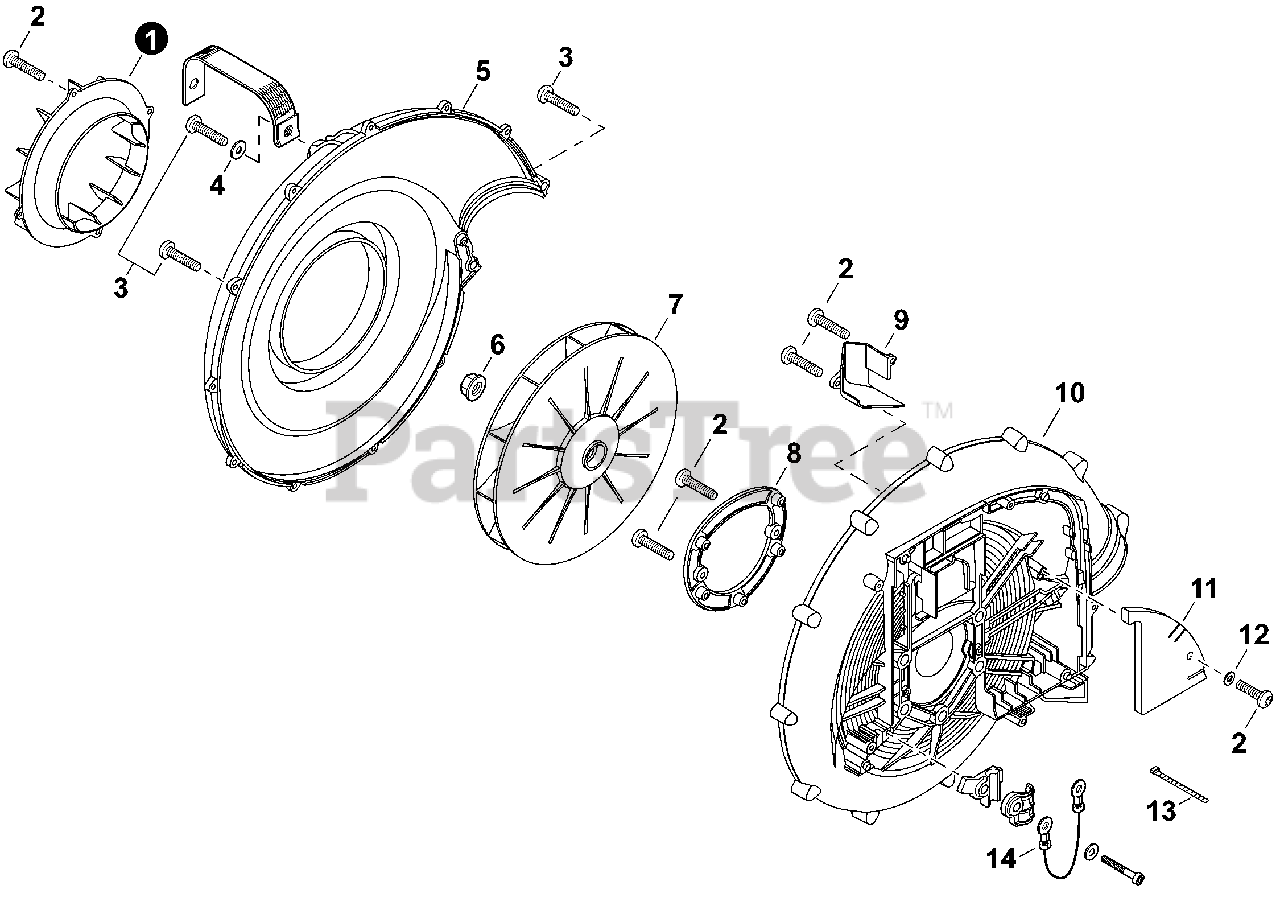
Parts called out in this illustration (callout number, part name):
1	DEFLECTOR, AIR
2	BOLT, TORX 5×16
3	BOLT, TORX 5×20
4	WASHER 5.5×16×2T
5	COVER, FAN
6	NUT, FLANGE 10×1.25
7	FAN, BLOWER
8	PLATE, ENGINE
9	COVER, AIR GUIDE
10	CASE, FAN
11	PAD, FOAM
12	WASHER 5.2×14×T3
13	STRAP, TIE
14	LEAD L= 195 MM
